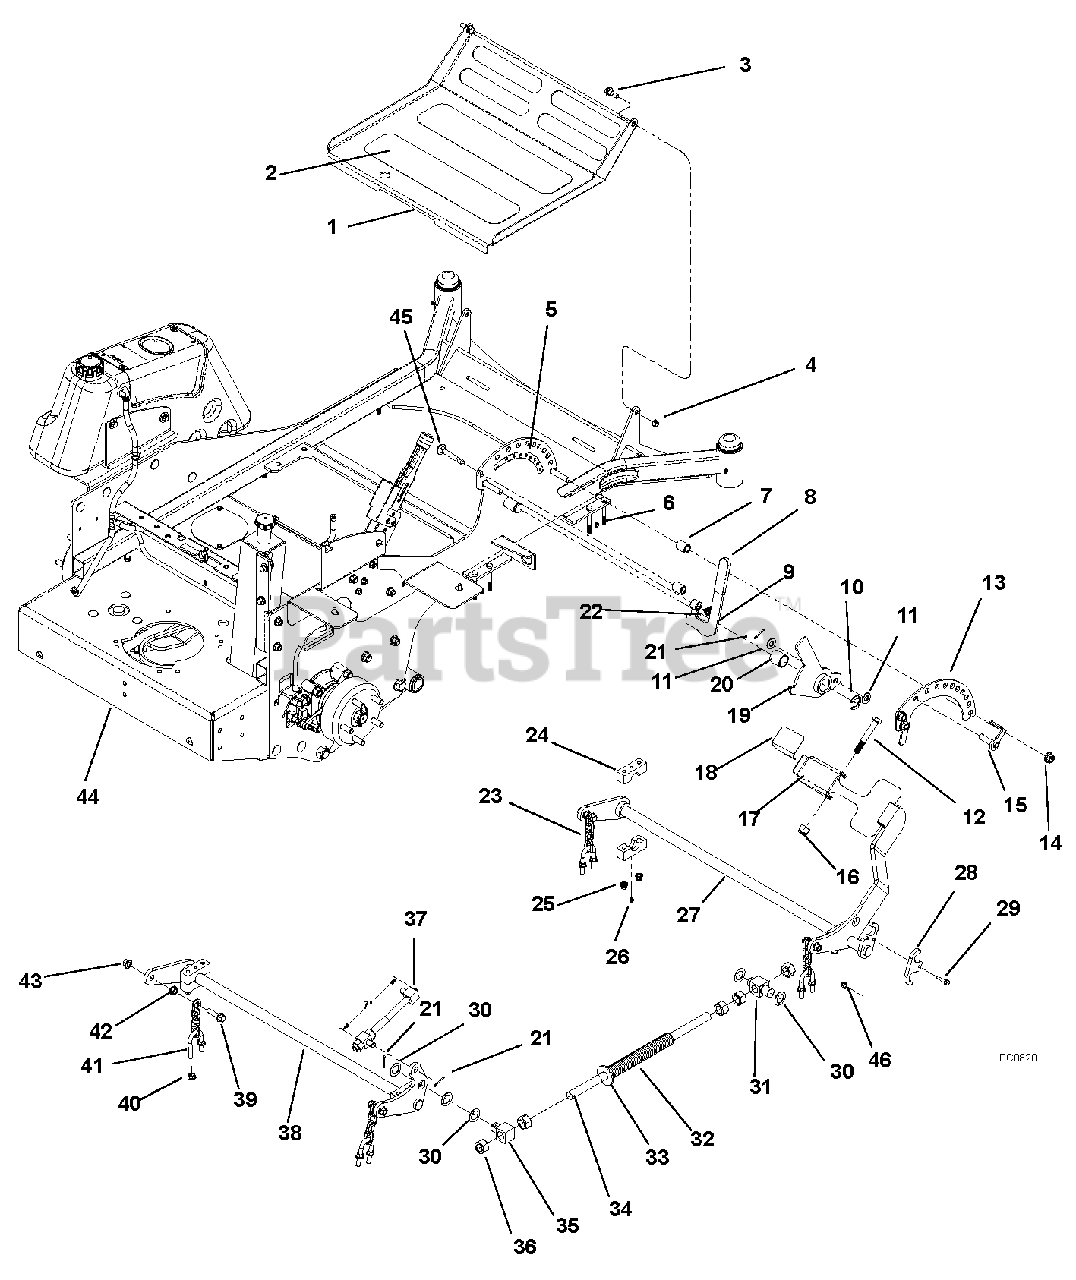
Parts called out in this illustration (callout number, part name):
3	2
10	1
12	1
16	1
36	5
